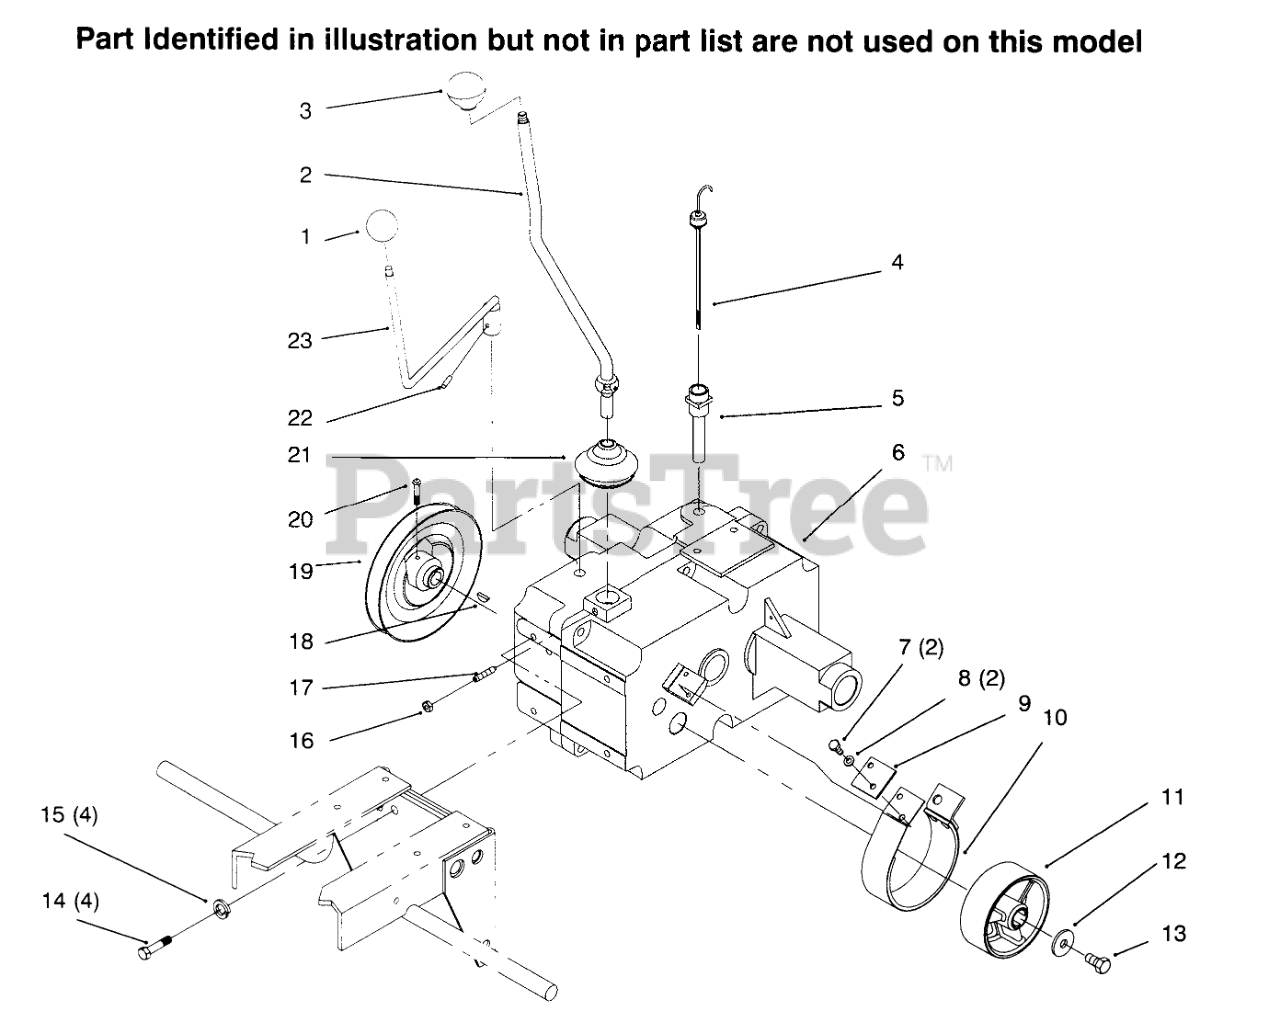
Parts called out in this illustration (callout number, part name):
2	ASM-Rod
4	Dipstick
5	NIPPLE-FILL, TRANSMISSION
6	Trans ASM 8 Pin 8 Spd
7	SCREW-HH
8	WASHER-LOCK
9	Plate-Stop
10	BRAKE BAND ASM
11	DRUM-BRAKE
12	WASHER
13	SCREW-HEX HD CAP
14	SCREW-HH
15	WASHER-LOCK
16	NUT-HEX
17	SETSCREW
18	KEY-HI PRO
19	PULLEY-TRANSMISSION
20	SCREW-SQH
21	COVER-DUST
22	PIN-SPIROL
23	SHIFT ROD ASM
24	DECAL-UNIDRIVE
